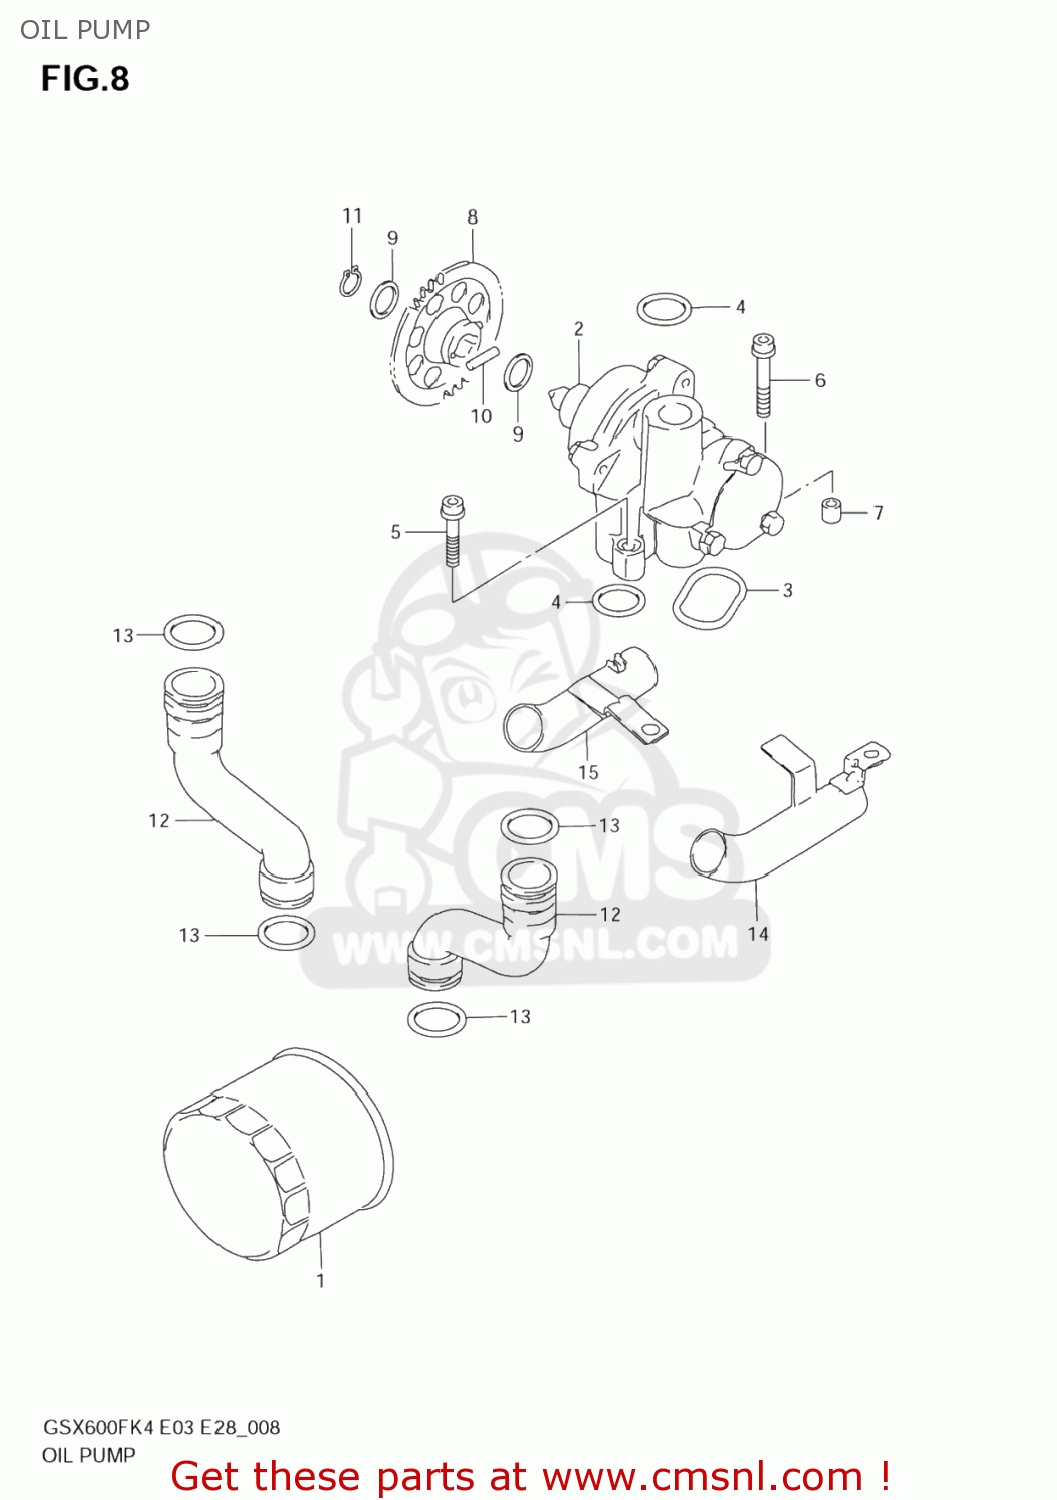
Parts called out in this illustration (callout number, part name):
1	FILTER ASSY,EN
2	PUMP ASSY,OIL
3	O RING,OIL PUMP
4	O RING(D:3.2,ID:17.8)
5	BOLT(6X30)
6	BOLT(6X35)
7	PIN
8	GEAR,OIL PUMP DRIVEN(NT:37)
9	SHIM
10	PIN(5X18)
11	CIRCLIP,12 MM
12	PIPE,OIL OUTLET
13	O RING(D:3.7,ID:21.7)
14	PIPE,OIL OUTLET UNDER,L
15	PIPE,OIL OUTLET UNDER,R
